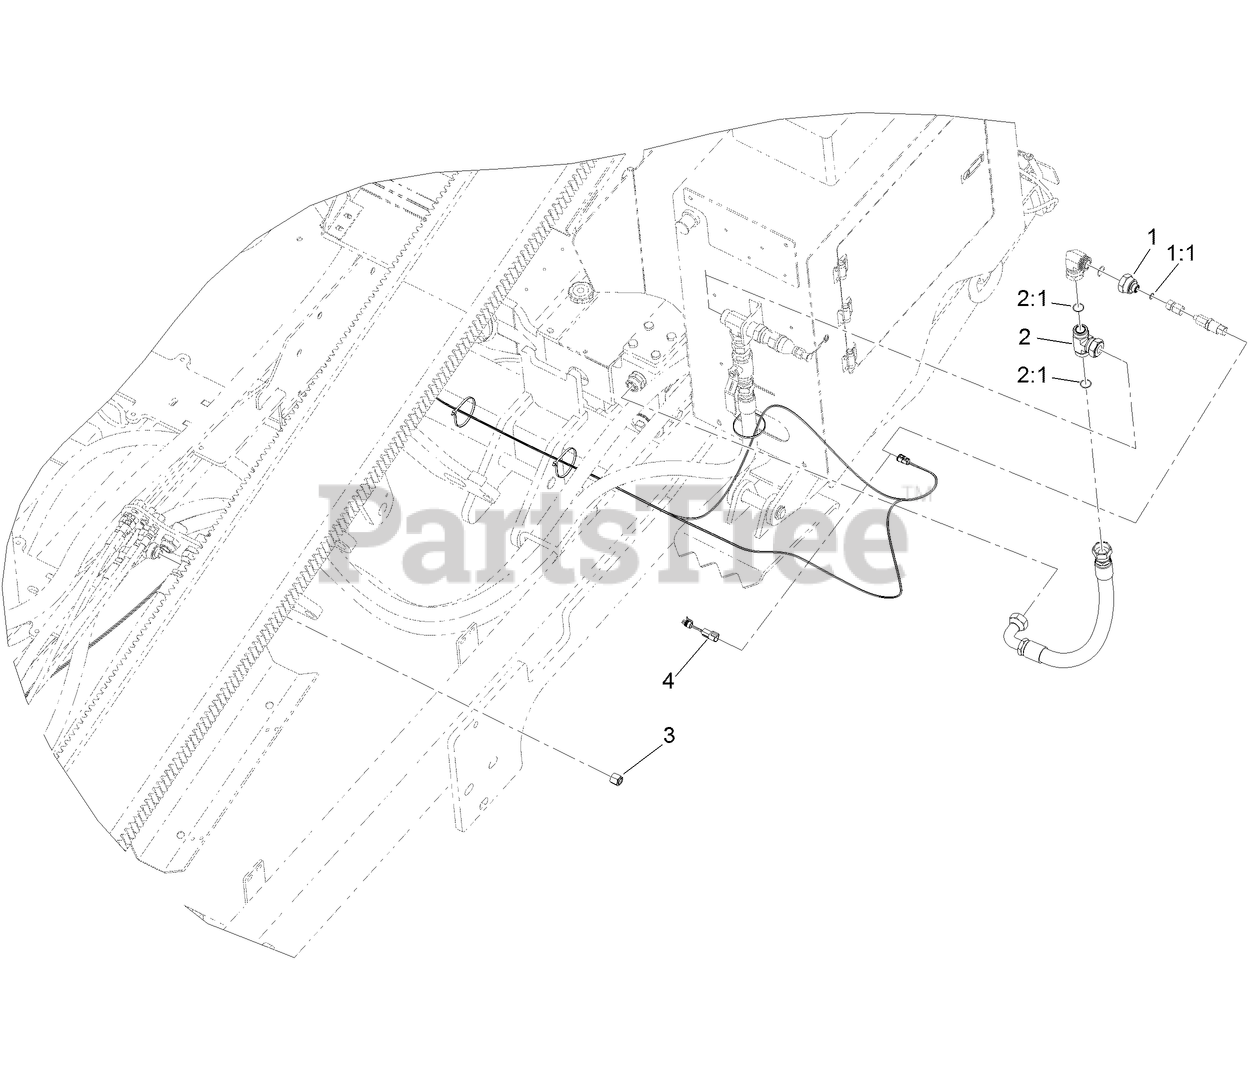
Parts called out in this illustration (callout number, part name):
1	FITTING-REDUCER
1:1	O-RING
2	FITTING-TEE
2:1	O-RING
3	CAP-HYD
4	HARNESS-WIRE
